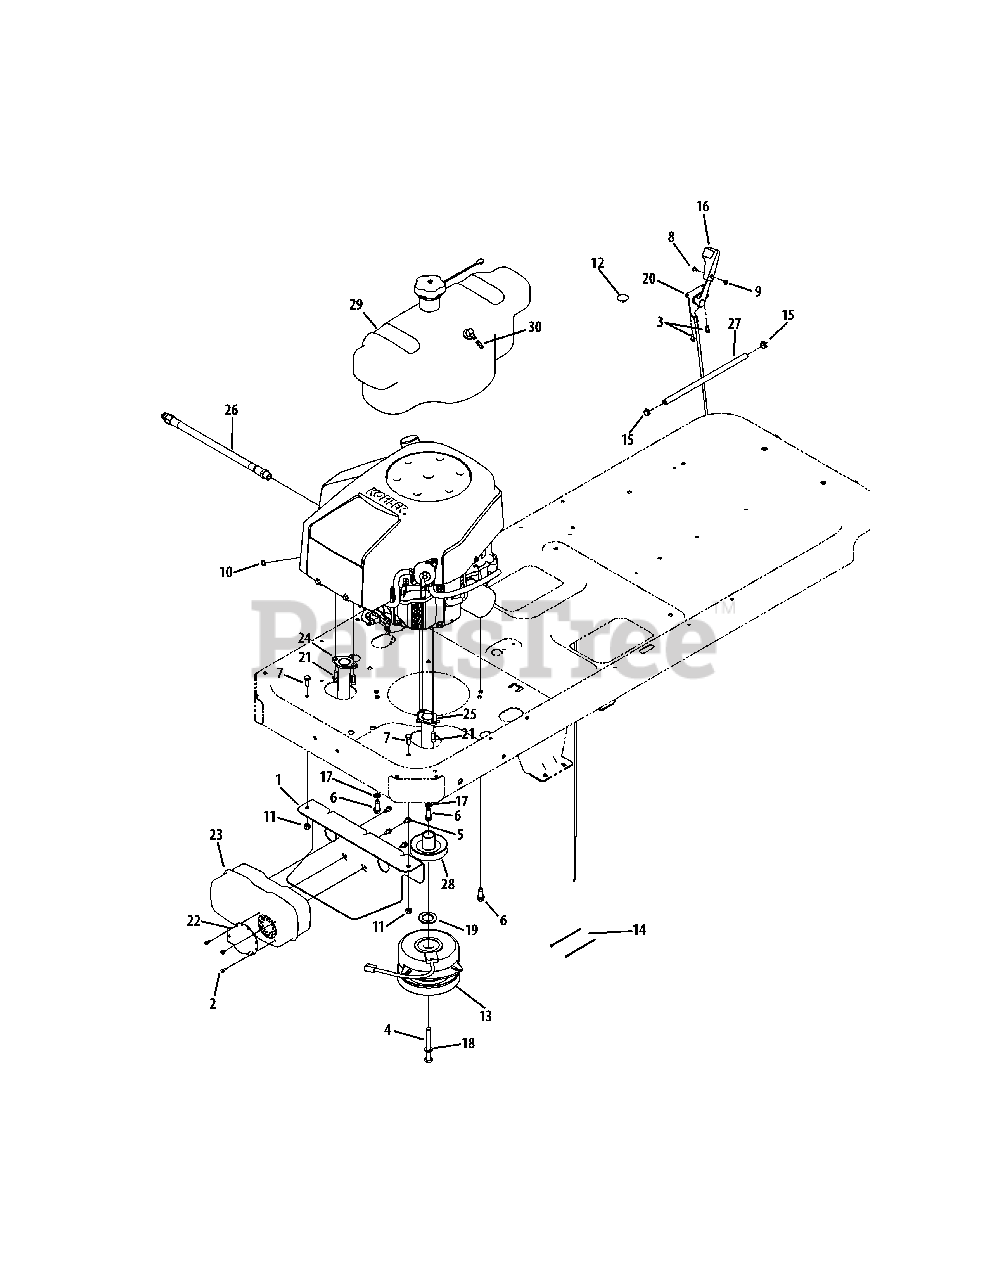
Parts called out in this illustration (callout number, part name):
1	Muffler Mount Bracket
2	Hex Washer Screw, #8-18 x .500
3	Screw, 1/4-14 x .625
4	Hex Lock Screw, 7/16-20 x 3.50
5	Hex Washer Screw, 1/4-20 x .500
6	Hex Washer Screw, 3/8-16 x 1.000
7	Hex Washer Screw, 5/16-18 x .75
8	Machine Screw, #8-32 x .375
9	Hex Nut, #8-32
10	Sems Nut, 1/4-20
11	Flange Lock Nut, 5/16-18
12	Choke Plug
13	Electric PTO Clutch
14	Cable Tie
15	Hose Clamp
16	Throttle Control Knob
17	Lock Washer, 3/8
18	Lock Washer, 7/16
19	Flat Washer, 1.03 x 1.620 x .095
20	Throttle/Choke Control Cable
21	Screw, 5/16-18 x .750
22	Muffler Deflector
23	Dual Inlet Muffler
24	Exhaust Pipe, LH
25	Exhaust Pipe, RH
26	Oil Drain Hose
27	Fuel Hose
28	Engine Pulley
29	Fuel Tank Assembly
29	Fuel Tank Bushing
29	Rubber Grommet
29	Fuel Tank
29	Fuel Pick-Up Fitting
29	Fuel Cap
29	Rollover Valve
30	Hose Vent, 3/16 EPA
